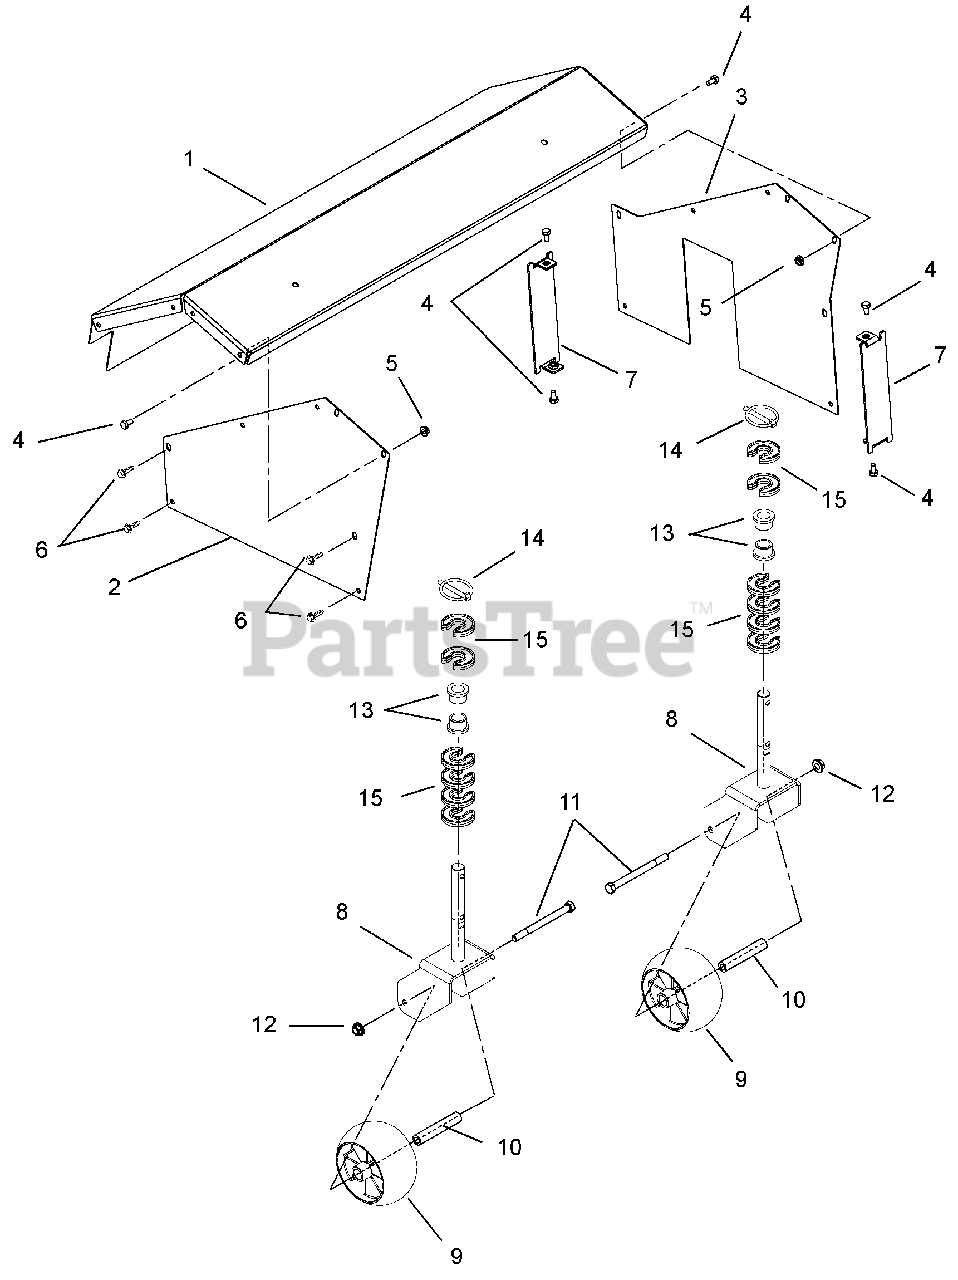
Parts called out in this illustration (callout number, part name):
1	COVER WITH DECALS, 28"BRUSH
1	DECAL, DANGER -POWER BRUSH-CE
1	DECAL, PTO WARNING
1	DECAL, CAUTION - BRUSH
1	Decal, Ariens Heritage
2	COVER,RH SIDE BRUSH
3	COVER,LH SIDE BRUSH
4	@BLT-HEX .25-20X.50 GR5 YWZC
5	@NUT-LK-TOP-FLG .25-20 YWZC
6	SCR-TAP .25-20X.50 HWH TR YWZ
7	COVER,END
8	FORK, CASTER-BRUSH
9	WHEEL, CASTER - 5"OD
10	SPACER, CASTER WHEEL
11	@BLT-HEX .38-16X4.50 GR5 YWZC
12	@NUT-LK-TOP-FLG .38-16 YWZC
13	BUSHING, FLANGE .75X.75X1.0
14	PIN, LYNCH - .25 X 1.25
15	CLIP-HOC FIXED
